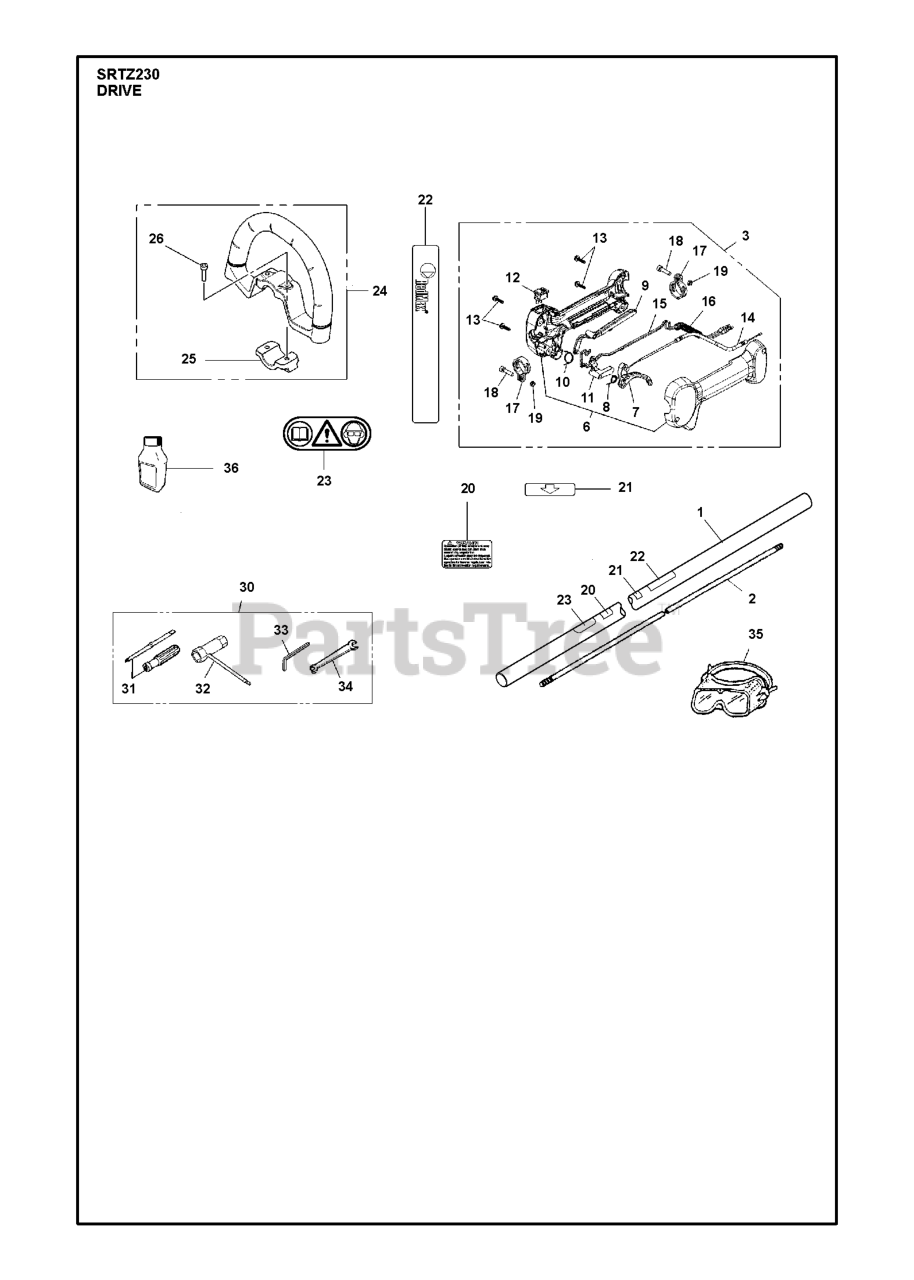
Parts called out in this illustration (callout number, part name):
1	PIPE-C
2	DRIVE SHAFT
3	ASSY THROTTLE
6	GRIP HALF SET
7	LEVER, THROTTLE
8	SPRING, THROTTLE
9	LEVER, SAFETY
11	LEVER JOINT
12	STOP SWITCH NM_09091801
15	CORD - C
19	NUT
20	DECAL SPARK ARRESTOR WARNING
23	LABEL (CAUTION)
24	HANDLE LOOP
25	CLAMP HANDLE
30	TOOL-SET
35	GOGGLExxx (RPLS
36	OIL 2 CYCLE ENGINE OIL 2.
